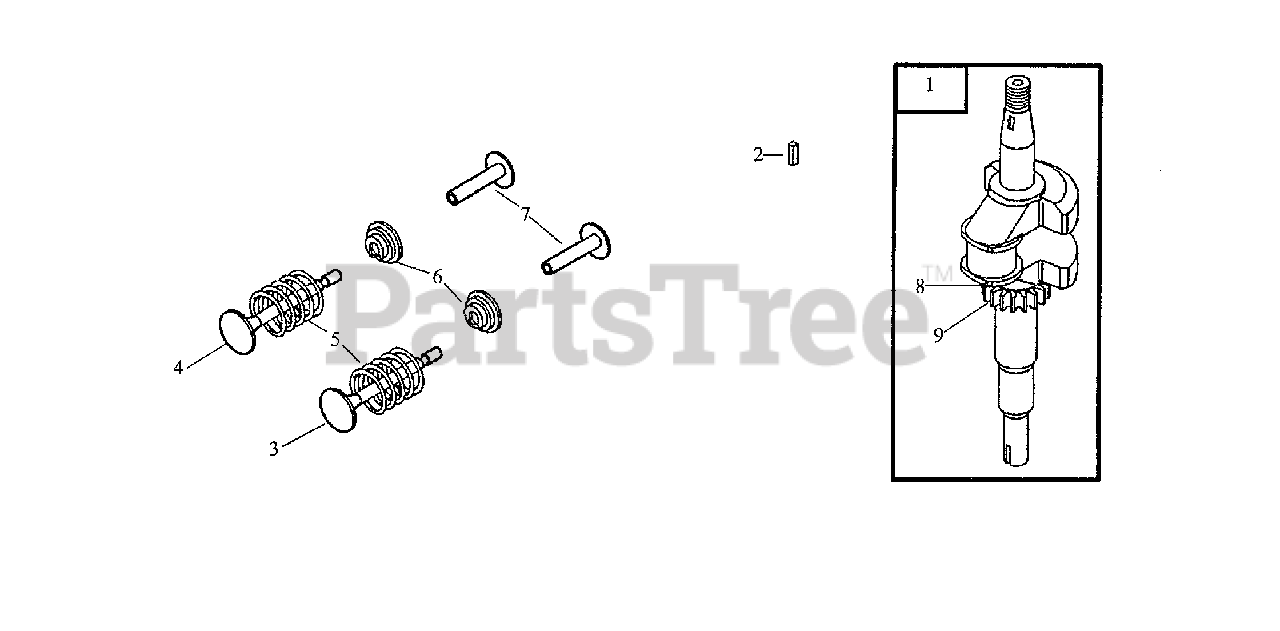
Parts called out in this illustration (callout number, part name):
1	Crankshaft
2	Key, Flywheel
3	Valve, Exhaust
4	Valve, Intake
5	Spring, Valve
6	Retainer, Valve
7	Tappet, Valve
8	Key, Timing
9	Gear, Timing
